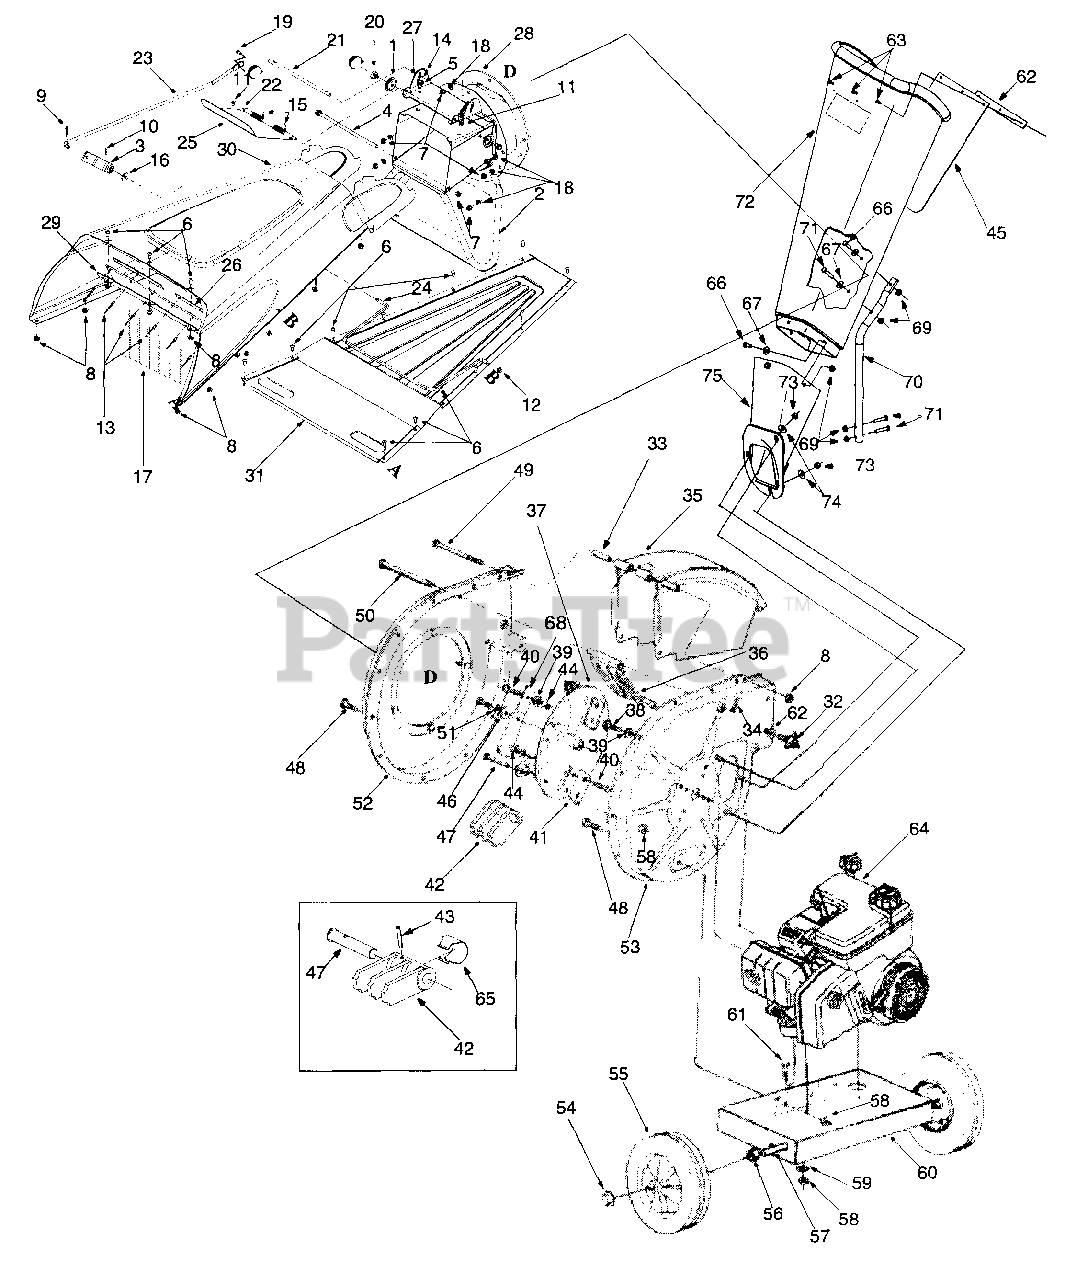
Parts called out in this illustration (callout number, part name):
1	Stop Washer
4	Hex Flange Bolt: 5/16-18 x 8.375" (gr.5)
5	Hex Washer Head Self-Tapping Screw: 5/16-18 x 0.5"
6	Button-Head Screw 1/4-20 x 0.5"
7	Lock Nut: 5/16-18
8	Hex Flange Lock Nut: 1/4-20
9	Internal Cotter Pin
10	Spiral Pin
11	Cap Nut
12	Speed Cap Nut
13	Pop Rivet
14	Torsion Spring
15	Hopper Door Spring
16	Rubber Washer
17	Hopper Flap
18	Lock Washer
19	Shdr. Scr: .340 x .285 x 1/4-20
20	Shdr. Scr: .56 x .165 x 5/16-18
21	Ret. Rod: 5/16" dia.
22	Hopper Door Rod
23	Flap Retaining Rod
24	Flap Retaining Bail
31	Lower Hopper
32	Hand Knob
33	Chute Hinge Spacer
34	Internal Cotter Pin
35	Discharge Chute Assembly
37	Impeller Assembly
38	Hex Bolt 5/16-24 X .75"
39	Lock Washer 5/16" Id
40	Flat Hd. Screw 5/16-24 X .75"
41	Chipper Blade
42	Flail Blade
43	Spring Roll Pin
44	Hex Top Lock Nut 5/16-24 (gr. 5)
45	Shredder Chute Flap
46	Flat Washer .406" ID X 1.25" OD
47	Clevis Pin
48	Hex Bolt 5/16-18 X 1.5"
49	Hex Bolt 1/4-20 X 3.75"
50	Clevis Pin
51	Lock Washer
54	Push Cap 5/8" Dia.
55	Wheel Assembly Comp.
56	Spacer
57	Shredder Axle
58	Hex Lock Nut 5/16-18 (Gr.5)
59	Special Lock Washer
61	Hex Bolt 5/16-18 x 1.5"
62	Chute Flap Strip
63	Pop Rivet
64	Engine: Tecumseh 6.5 hp.
65	Pin Retaining Clip
66	Hex Bolt 1/4-20 x .625
67	Flat Washer .28 I.D. x .74 O.D.
68	Shredder Blade
69	Flanged Lock Nut
71	Hex Screw 1/4-20 x .625 (gr. 2)
74	Bell Washer.345" I.D. x.88"
75	Chipper Chute
